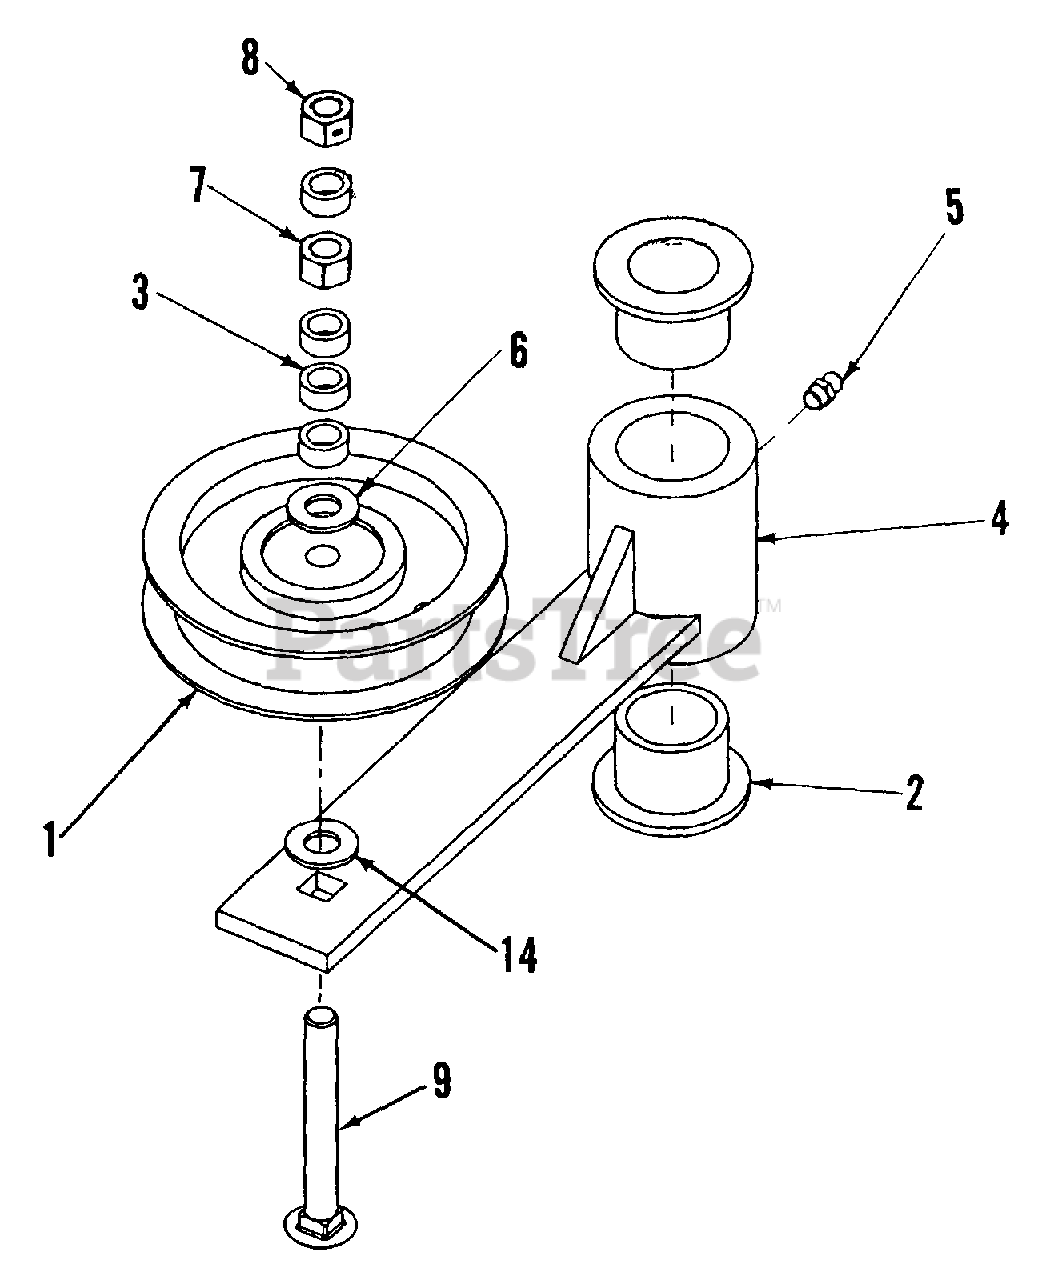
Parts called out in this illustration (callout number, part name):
1	FLAT IDLER, 4-1/8"
2	BUSHING, Caster
3	SPACER, Tie Rod
4	WELDMENT, Idler Arm
5	FITTING, Lube 1/4-28 Straight
6	WASHER, 3/8" Flat
7	NUT, 3/8-16 Hex, Grade 5 or B
8	NUT, 3/8-16 Hex Center Lock, Grade 5 or B
9	BOLT, 3/8-16 x 3", Round Head Square Neck Grade 5
14	WASHER, 3/8" Flat
